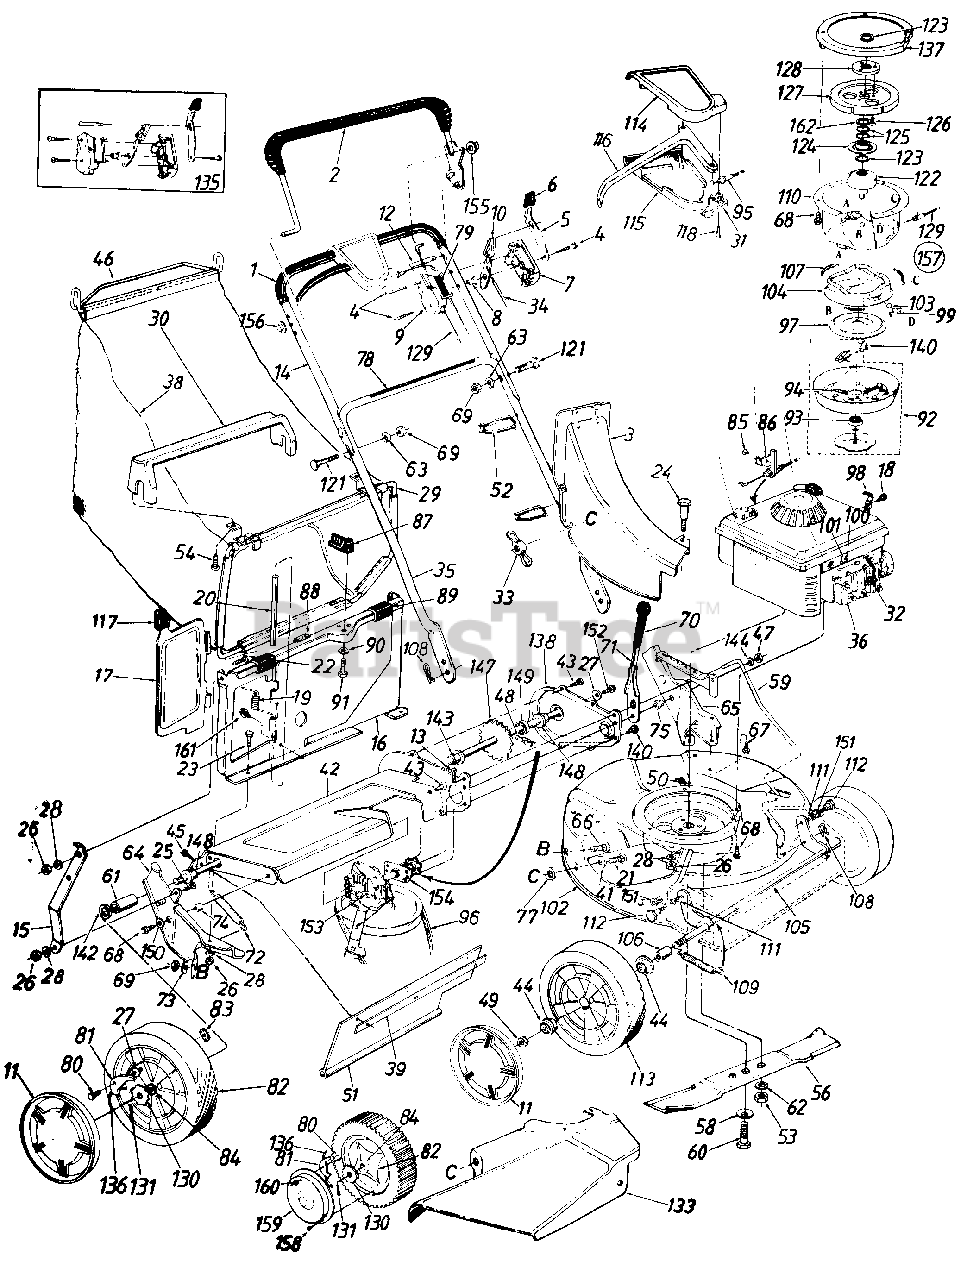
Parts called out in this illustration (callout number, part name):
1	Foam Grip
2	Control Handle Ass'y.-L.H.
3	Top Discharge Chute Ass'y.
4	Truss Mach. Scr. #12 x 1.50" Lg.
5	Lockout Spring
6	Spring Lever Knob
7	Control Panel Half
8	Control Disc Pin
9	Clutch Panel Half
10	Throttle Control Lever
11	Hub Cap
12	Lock Pin .314" Dia. x 1.75"
13	Cotter Pin 3/32" Dia. x .75"
14	Upper Handle-Chrome
15	Panel Support Brkt.
16	Top Catcher Panel Ass'y.
17	Top Discharge Door
18	Hex B-Tap Scr. #10 x .38"
19	Torsion Spring
20	Pivot Pin
21	Carriage Bolt 1/4-20 x .62"
22	Truss Mach. Scr. 1/4-20 x .5" Lg.
23	Hex Bolt 1/4-20 x .50" Lg.
24	Shoulder Bolt .312 Dia. x .18 Lg. Special
25	Hex Bolt 1/4-20 x .62" Lg.
26	Hex Nut 1/4-20 Thd.
27	Bell-Wash. 1/4" I.D.
28	L-Wash. 1/4" I.D.
29	Front Grass Catcher Frame
30	Grass Catcher Handle
31	S.P. Control Cover
32	Spark Plug Insulator
33	Wing Nut
34	Throttle Control Wire 58" Lg.
35	Lower Handle-Chrome
36	Engine
38	21" Top Discharge Grass Bag-Black
39	Retaining Strip
41	Fl-Wash. .344" I.D. x .62"
42	Chain-Axle Ass'y.
43	Hex B-Tap Scr. 1/4" x .38" Lg.
44	Flange Ball Bearing 1/2" I.D.
45	Hex AB-Tap Scr. 1/4 x .62"
46	Upper Bag Handle
47	Hex Patch L-Nut 3/8-24 Thd.
48	#48 Chain .500" Pitch x 30 Links
49	Hex L-Nut 1/2-20 Thd.
51	Rear Flap 3.75" x 17.30" Lg.
52	Cable Tie
53	Hex Nut 3/8-24 Thd. (Grade 8)
54	Hex AB-Tap Scr. #12 x 1.0" Lg.
56	21" Blade
58	Bell-Wash. .46" I.D. x .88" O.D.
59	Height Adj. Rod 19.42" Ig.
60	Hex Bolt 7/16-20 x 2.0" Lg. (Grade 5)
61	Spacer .513" I.D. x .703" O.D. x .69" Lg.
62	L-Wash. 3/8" I.D.
63	L-Wash. 5/16" I.D.
64	R.H. Handle Wheel Brkt. Ass'y.
65	L.H. Handle Wheel Brkt. Ass'y.
66	Carriage Bolt 5/16-18 x .62"
67	Hex Wash. Hd. B-Tap Scr. 5/16-18 x .5" Lg.
68	Hex Wash. Hd. TT-Tap Scr. 3/8-16 x 1.5" Lg.
69	Hex Nut 5/16-18 Thd.
71	Height Adj. Lever
72	Extension Spring .50" O.D. x 3.80" Lg.
73	Bell-Wash. 5/16" I.D.
74	Spacer .385" I.D. x .502" O.D. x .270" Lg.
75	Shld. Spacer .500" Dia. x .1 00
77	Bolt Retainer 1/4 x .50" O.D.
78	Instruction Label
79	Control Label
80	Shld. Scr. .342" Dia. x .268
81	Pawl
82	Wheel Ass'y. Comp.
83	Flat Weld Nut 1/4-20 Thd.
84	Sleeve Bearing 1/2" I.D.
85	Pop Rivet .156" Dia. x .379"
86	Cable Bracket
87	Grass Catcher Locking Knob
88	Foam Strp 1" Lg.
89	Panel Clip
90	Spring Wash. .32" I.D.
91	Hex Tap Scr. 1/4-20 x .75" Lg.
92	Clutch Blade Housing Ass'y.
93	Ball Brg. .669" I.D. x 1.574"
94	Comp. Spring .35" O.D. x 2.0" Lg.
95	S.P. Cable x 50" Lg.
96	"V"-Belt
97	Clutch Cone
98	Casing Clamp
99	Ball Block
100	Hex B-Tap Scr. #10 x .62"
101	Casing Clamp
104	Brake Cup Cone
105	Front Axle Ass'y.
106	Sleeve .526" I.D. x .690" O.D. x .880" Lg.
107	Ext. Spring 1.75" Lg.
108	Intern. Cotter Pin 5/16" Dia.
109	Extension Spring .50" O.D. x 3.20" Lg.
110	Clutch Housing
111	Intern. L-Wash. 3/8 I.D.*
112	Shld. Bolt .623" Dia. x .425
113	Wheel Ass'y. Comp.
114	Self-Propelled Control Cover
115	Self-Propelled Control Cover
116	Control Lever
117	Door Grip
118	Fl-"C"-Sunk Hd. Tap Scr. #10 x .75" Lg.
121	Curved Carr. Bolt 5/16-18 x 1.38" Lg.
122	Fixed Pulley Adapter
123	Serrated Washer 1.0" I.D.
124	Serrated Pulley Half
125	Wave Washer 1.005" I.D.
126	Flat HD Tap Scr. 1/4-20 x .625" Lg.
127	Flywheel
128	Flywheel Adapter
129	Control Cable-49" Lg.
130	Ratchet Wheel 1.62" O.D.
131	Cotter Pin 1/8" Dia. x 1.00" Lg.
133	Side Chute Deflector Ass'y.
135	Kit-Control Housing Comp.
136	Spring-Nylon
137	Engine Mounting Plate Cover
138	Chain Cover
140	Hex Wash. S-Tap Scr. 1/4-20 x.50" Lg.
142	Fl-Wash. .510" I.D. x 1.0" O.D.
143	Hex Flange Brg. .506" I.D.
144	Fl-Wash. .385" I.D. x .87" O.D.
147	Rear Shaft Ass'y. 21.94" Lg.
148	Hex Flange Bearing .506" I.D. Plastic
149	Fl-Wash. .531" I.D. x .9301' O.D.
150	Fl-Wash. .531" I.D. x 1.25" O.D.
151	Flanged Nyliner Brg.
152	Hex Bolt 1/4-20 x .62" Lg. (Grade 5)
153	Transmission Comp.
154	Hex Bearing Cup
155	Push Cap
156	Push Cap
157	Blade Brake Clutch Ass'y. Comp.
158	Pan Hd. Tap Scr. #12 x .50" Lg.
159	Hub Cap
161	Hex B-Tap Scr. #10 x .38"
162	Serrated Washer 1.0" I.D.
